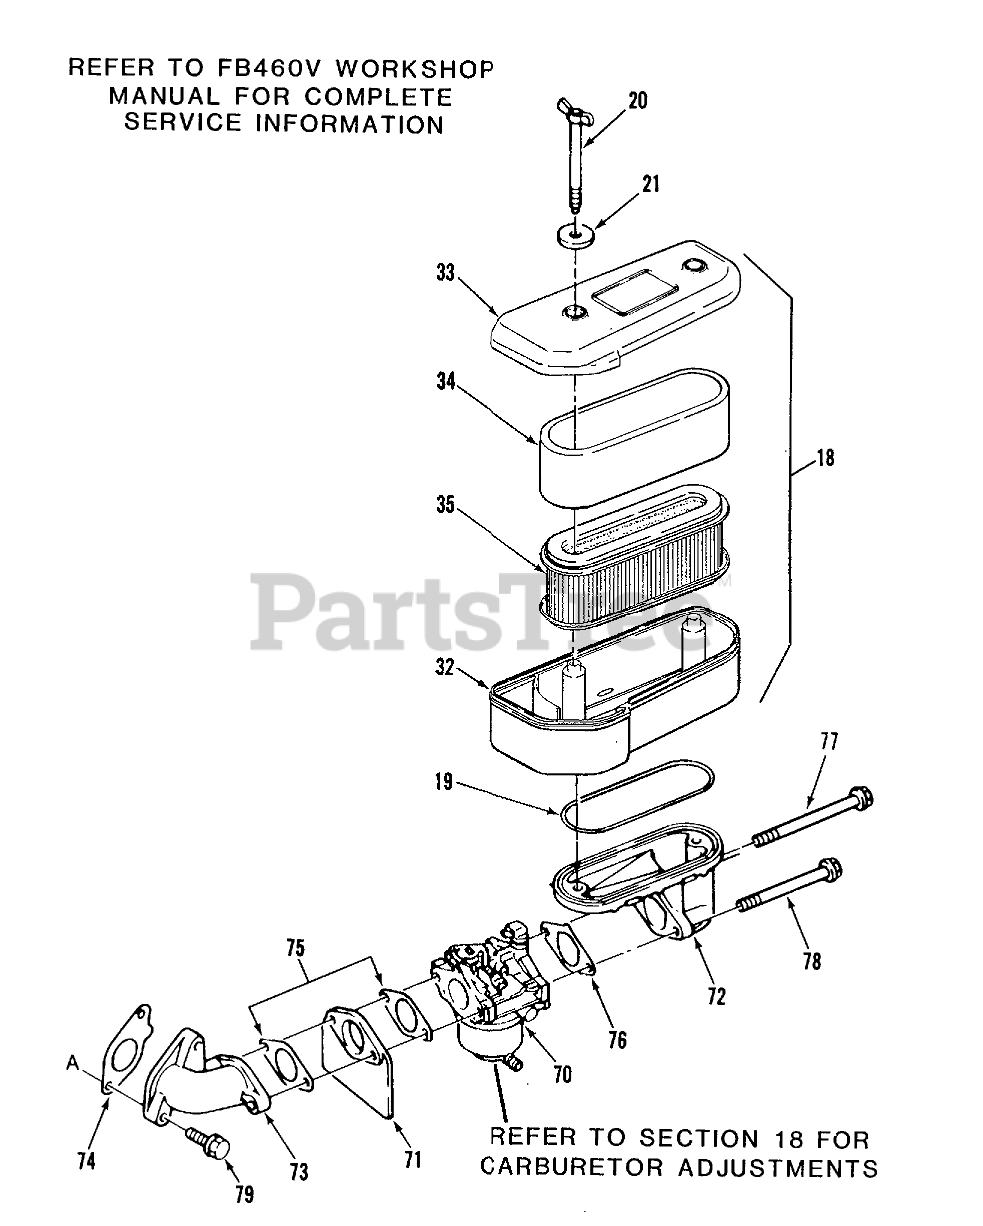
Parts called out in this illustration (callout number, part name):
18	Air Filter Assy (includes items 32, 33, 34 & 35
19	Gasket
21	Washer
32	Air Filter Case
33	CAP-Air Filter
70	Carburetor Assy-see section 9-6 for parts breakdown
72	Pipe-Intake
73	Pipe-Intake
74	Gasket
75	Gasket
76	Gasket
79	Bolt-Flanged (8X25)
